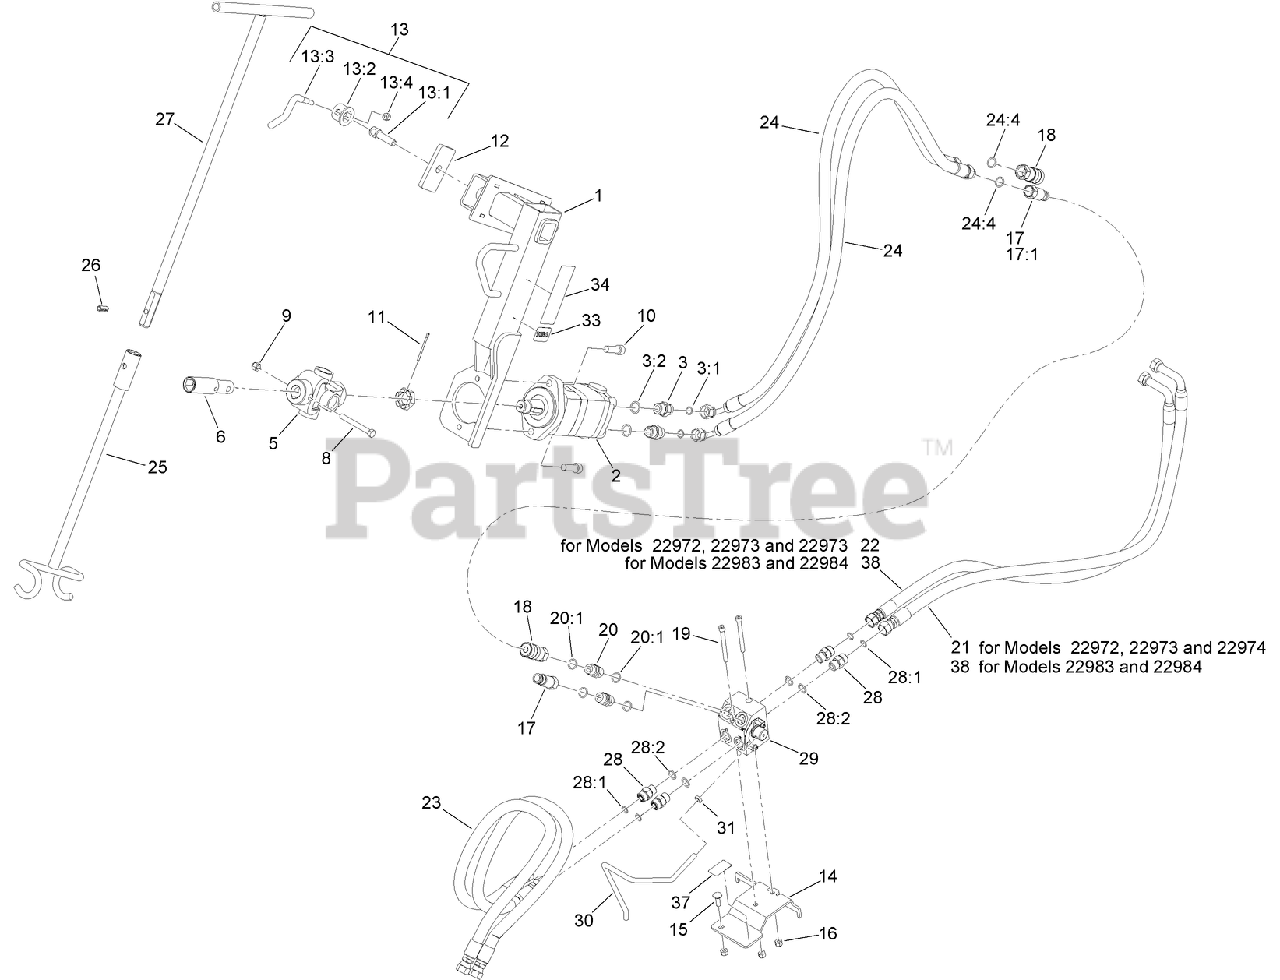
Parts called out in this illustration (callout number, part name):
1	BORE ASM
2	MOTOR-HYD
3	FITTING-STRAIGHT
3:1	O-RING
3:2	O-RING
5	JOINT-UNIVERSAL
6	COUPLER
8	SCREW-HH
9	NUT-LOCK, NI
10	SCREW-HSH
11	PIN-COTTER
12	PLATE-CLAMP
13	LEVER ASM
13:1	SCREW-LOCK
13:2	CAP-LOCK
13:4	NUT-LOCK, NI
14	PLATE-MANIFOLD
15	BOLT-CARR
16	NUT-LOCK, NI
17	NIPPLE-CONNECTOR
17:1	SEAL KIT
18	COUPLER-FEMALE
19	SCREW-HSH
20	FITTING-THREAD, STRAIGHT
20:1	O-RING
21	HYD HOSE ASM
22	HYD HOSE ASM
23	HYD HOSE ASM
24	HYD HOSE ASM
24:4	O-RING
25	TOOL-GUIDE, ROD
26	PIN-ROLL
27	HANDLE-TOOL, GUIDE
28	FITTING-STRAIGHT
28:1	O-RING
28:2	O-RING
29	HYD MANIFOLD ASM
30	HANDLE-MANIFOLD
31	NUT-JAM
33	DECAL
34	DECAL-DANGER
37	DECAL-INSTRUCTIONAL
38	HOSE-HYD
